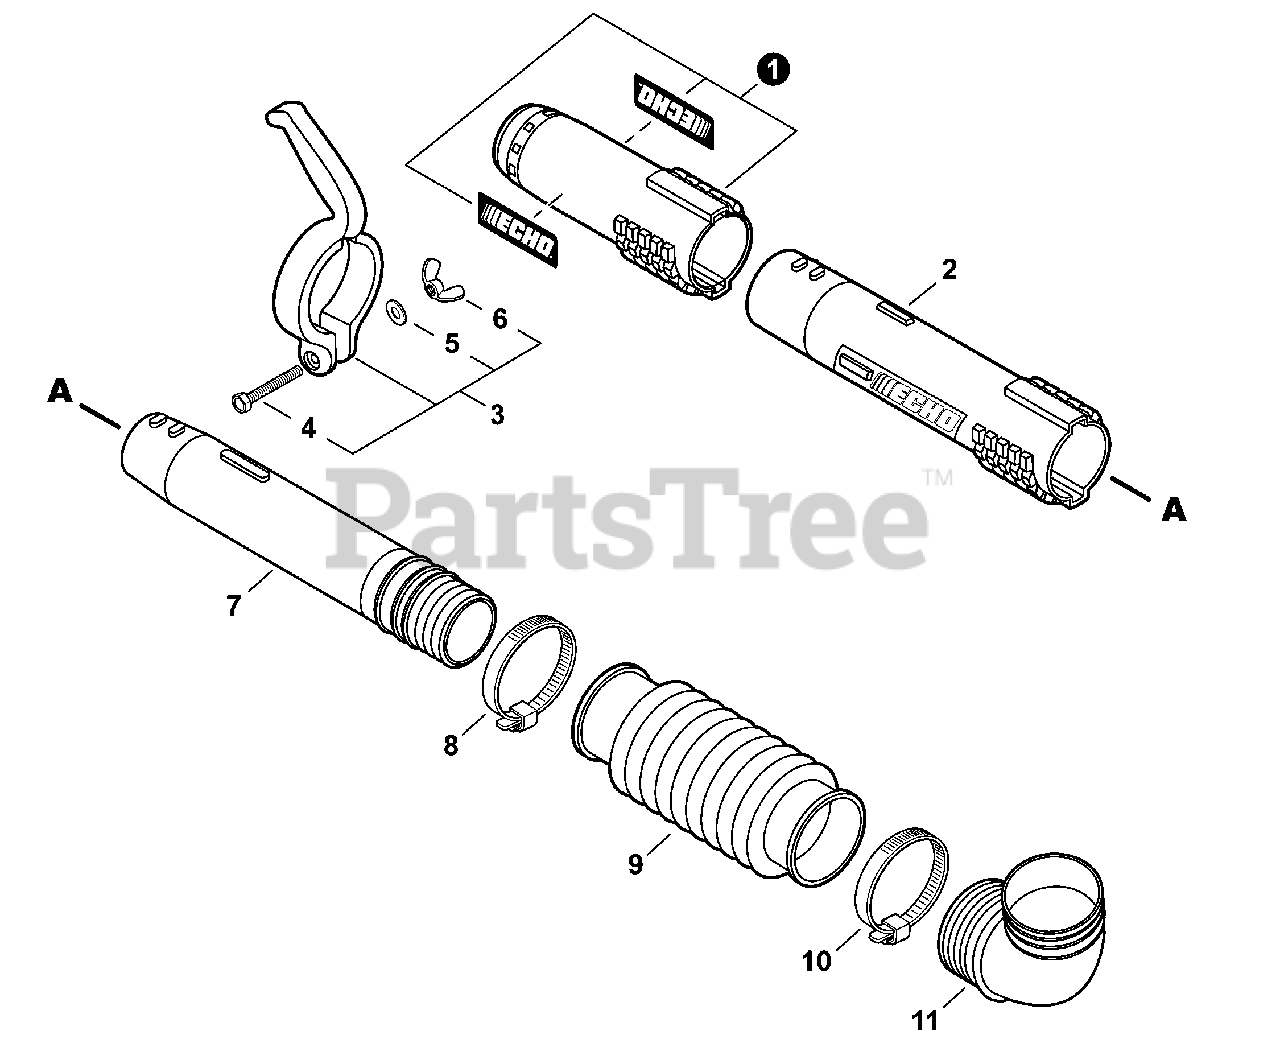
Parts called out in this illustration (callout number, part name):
1	TUBE SET, BLOWER - NOZZLE
2	TUBE, BLOWER - STRAIGHT
3	HANDLE SET, FRONT
4	BOLT 6×45
5	WASHER 6.5×11.5×0.8
6	NUT, WING 6
7	TUBE, BLOWER - SWIVEL
8	CLAMP 58.7 MM / 82.5 MM
9	TUBE, BLOWER - FLEXIBLE
10	CLAMP - BAND
11	TUBE, BLOWER - ELBOW
